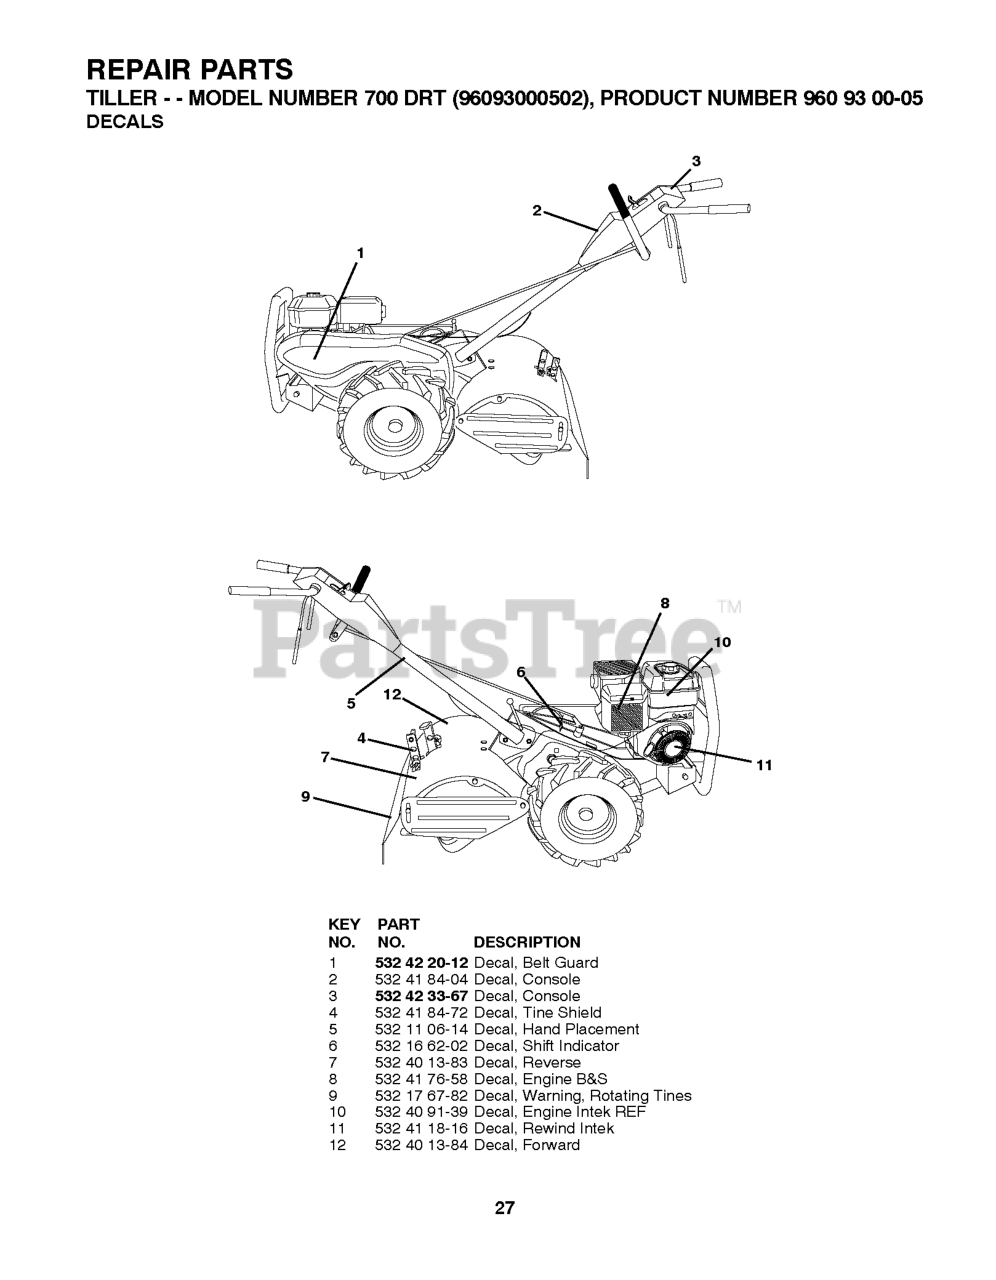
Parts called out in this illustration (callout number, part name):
1	DECAL.HOOD.LOGO.ORANGE.HUSQVAR
2	DECAL.CONSOLE.700DRT.HUSQ
4	DECAL.SHIELD.TN.DRT17.HUSQ.008
5	DECAL TI (2 2)
6	DECAL.SHIFT.INDICATOR.DRT
7	DECAL.REVERSE.HUSQ
9	DECAL.DRT.WARN.ENG/F
10	DECAL.BS.850.TANK.REF.276929
11	DECAL, REWIND STARTER, B&S
12	DECAL.FORWARD.HUSQ
